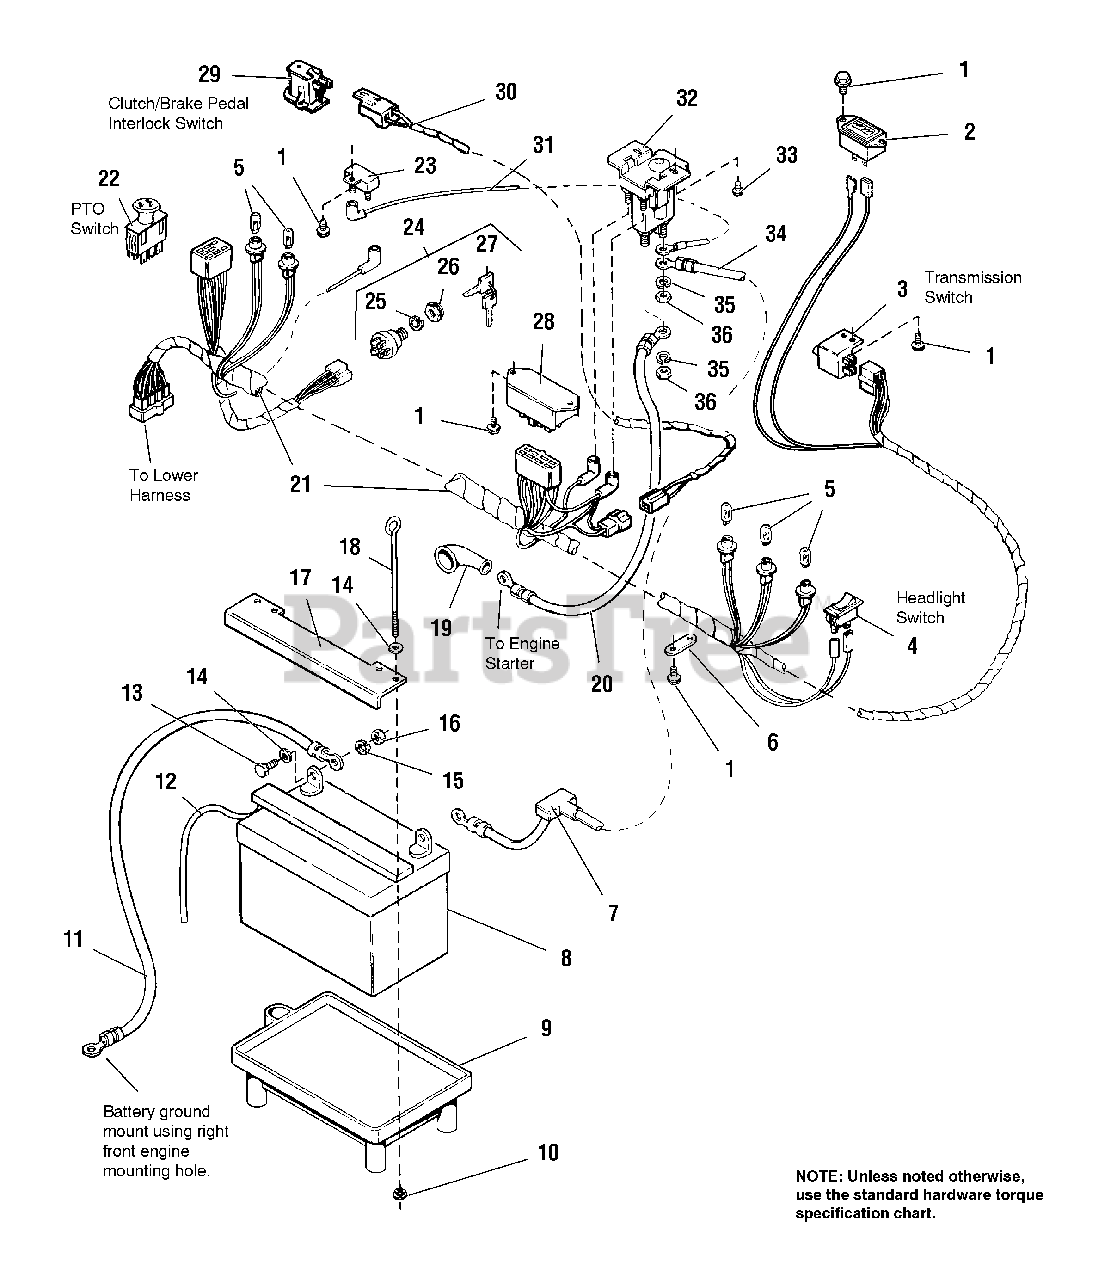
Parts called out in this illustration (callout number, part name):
1	SCREW, Plastite, #8-16 x 1/2
3	SWITCH, Transmission, Neutral Start
4	SWITCH, Headlight
5	BULB, Indicator Light
6	STRAP, Wire Retainer
7	BOOT, Insulator
9	TRAY, Battery
10	NUT, Plastic, 1/4-20
11	CABLE, Battery to Ground
12	HOSE, Battery, Drain
13	CAPSCREW, Hex, 1/4-20 x 3/4
14	WASHER, Plain, 9/32
15	LOCKWASHER, 1/4
16	NUT, Hex, Full, 1/4-20
17	HOLD DOWN, Battery
18	ROD, Battery Hold Down
19	COVER, Terminal
20	CABLE, Solenoid to Starter
21	HARNESS, Upper
22	SWITCH, PTO Electric Clutch
23	CIRCUIT BREAKER
24	IGNITION SWITCH ASSY.
25	LOCKWASHER, Internal Tooth, 5/8
27	KEY, Ignition
29	SWITCH, Interlock, Clutch/Brake Pedal
32	SOLENOID
33	SCREW, Plastite, 1/4-20 x 1/2
34	CABLE, Battery to Solenoid
35	LOCKWASHER, 5/16
36	NUT, Hex, 5/16-24
